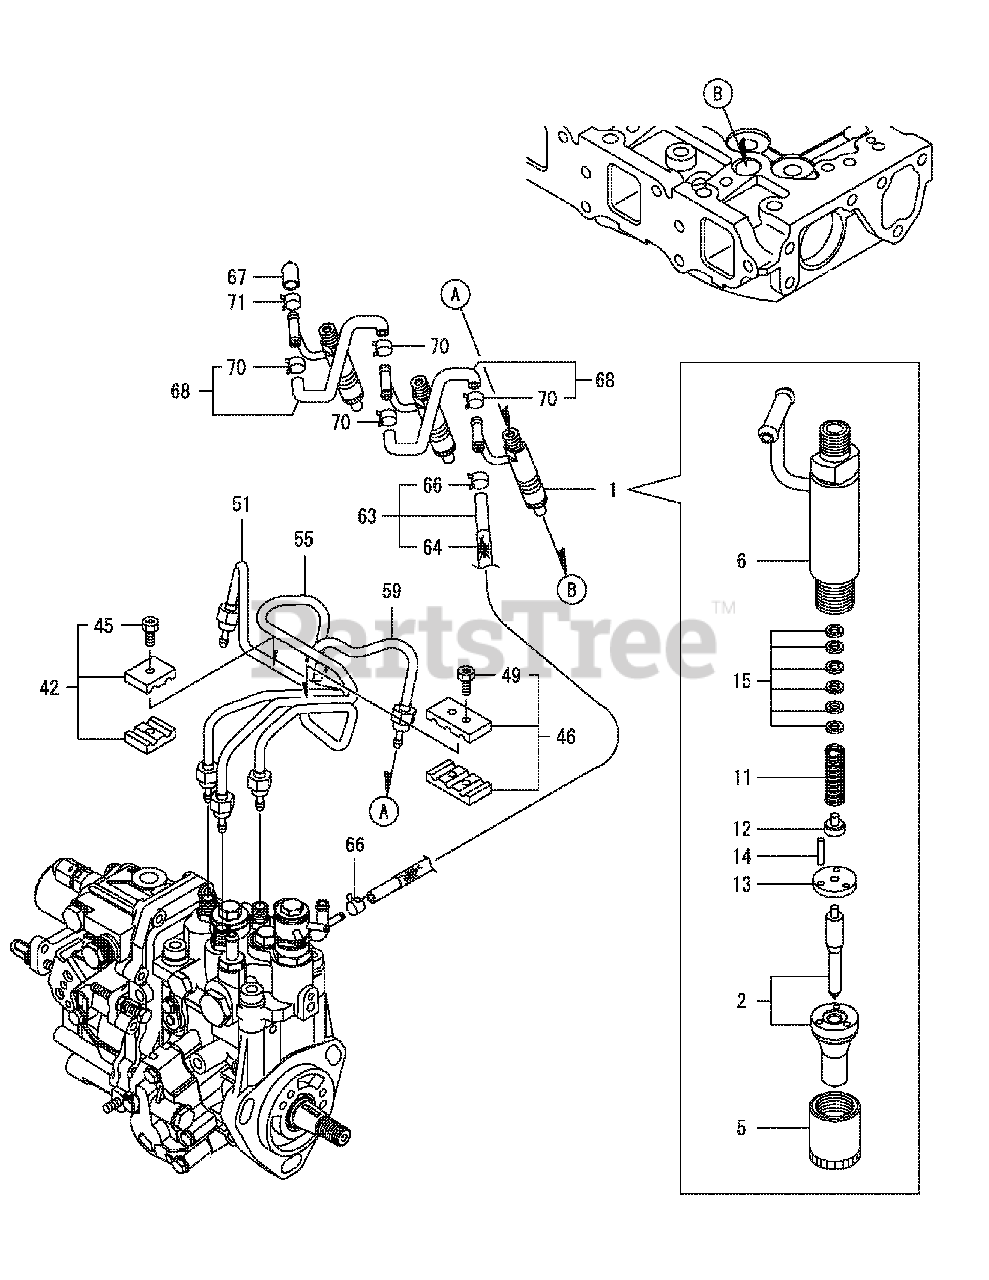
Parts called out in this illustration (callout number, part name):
1	Injection Valve Assembly
2	Injection Valve Assembly
6	Nozzle Holder Assembly
45	Hex Socket Bolt, M4 x 14
49	Hex Socket Bolt, M4 x 14
51	Injection Pipe Assembly
55	Injection Pipe Assembly
59	Injection Pipe Assembly
63	Return Pipe Assembly
64	Hose Protector
68	Fuel Return Hose
